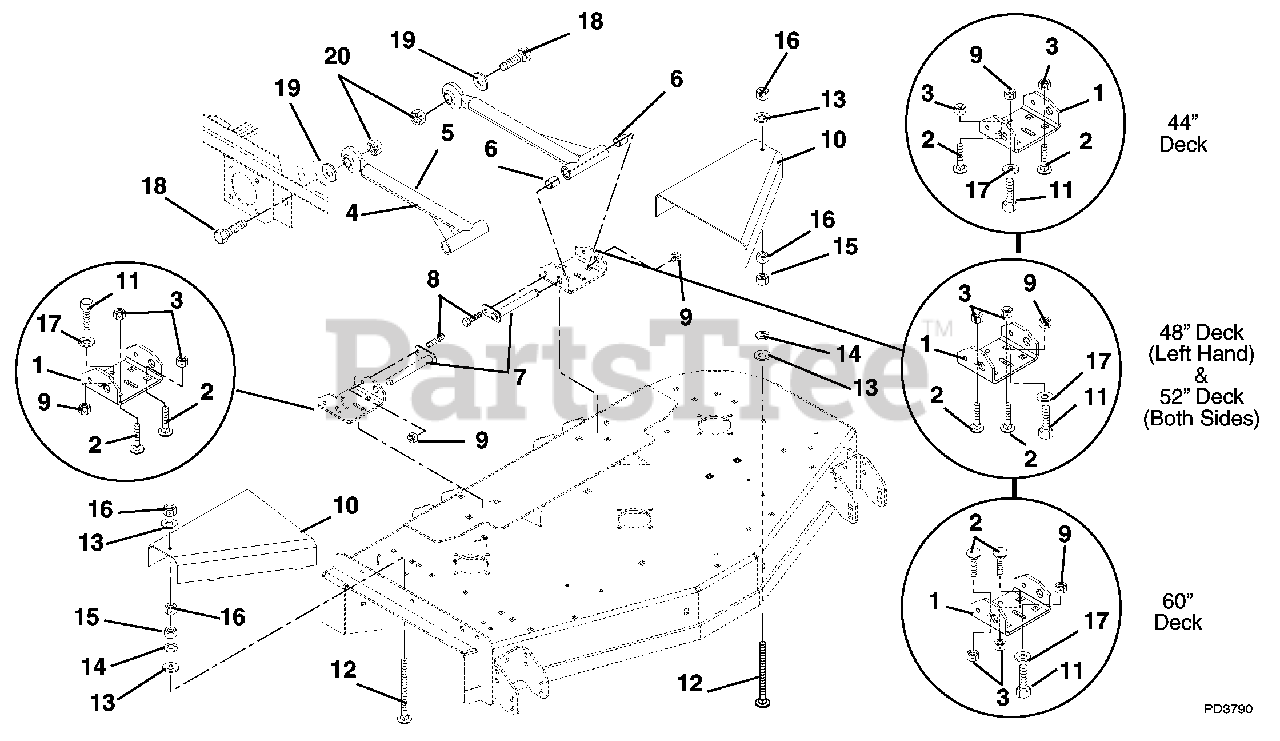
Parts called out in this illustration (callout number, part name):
1	Bracket, Mower Mounting (Rear)
2	Bolt, Round Head Square Neck .50-13 x .75 Grade 5
3	Nut, Locking Center Jam .50-13
4	Assembly, Mower Mounting
5	Mower Mounting Arm
6	Bearing, .75 x .875 x 1.00
7	Weldment, Mower Mounting Pin
8	Bolt, Hex .38-16 x .75 Grade 5
9	Nut, Locking Top Flange .38-16
10	Guard, Pulley Left Hand (044, 054)
10	Guard, Pulley Right Hand (044, 054)
10	Guard, Pulley Left Hand (051, 055)
10	Guard, Pulley Right Hand (051, 055)
10	Guard, Pulley (042, 043)
11	Bolt, Round Head Square Neck .38-16 x .75 Grade 5
12	Bolt, Round Head Square Neck Full Thread .312-18 x 3.50 (042, 043, 044, 054, 310, 311)
12	Bolt, Round Head Square Neck Full Thread .312-18 x 3.50 (051, 055)
13	Washer, Flat Steel .344 x .688 x .065 (042, 043, 044, 054, 310, 311)
13	Washer, Flat Steel .344 x .688 x .065 (051, 055)
14	Washer, Locking .31 x .078 (042, 043, 044, 054, 310, 311)
14	Washer, Locking .31 x .078 (051, 055)
15	Nut, Hex .31-18 (042, 043, 044, 054, 310, 311)
15	Nut, Hex .31-18 (051, 055)
16	Nut, Locking Center .31-18 (042, 043, 044, 054, 310, 311)
16	Nut, Locking Center .31-18 (051, 055)
17	Washer, Flat Steel .406 x .812 x .065
18	Bolt, Hex .875-9 x 2.75 Grade 5
19	Washer, Flat Steel .875 x 1.50 x .120
20	Nut, Locking Center .875-9
